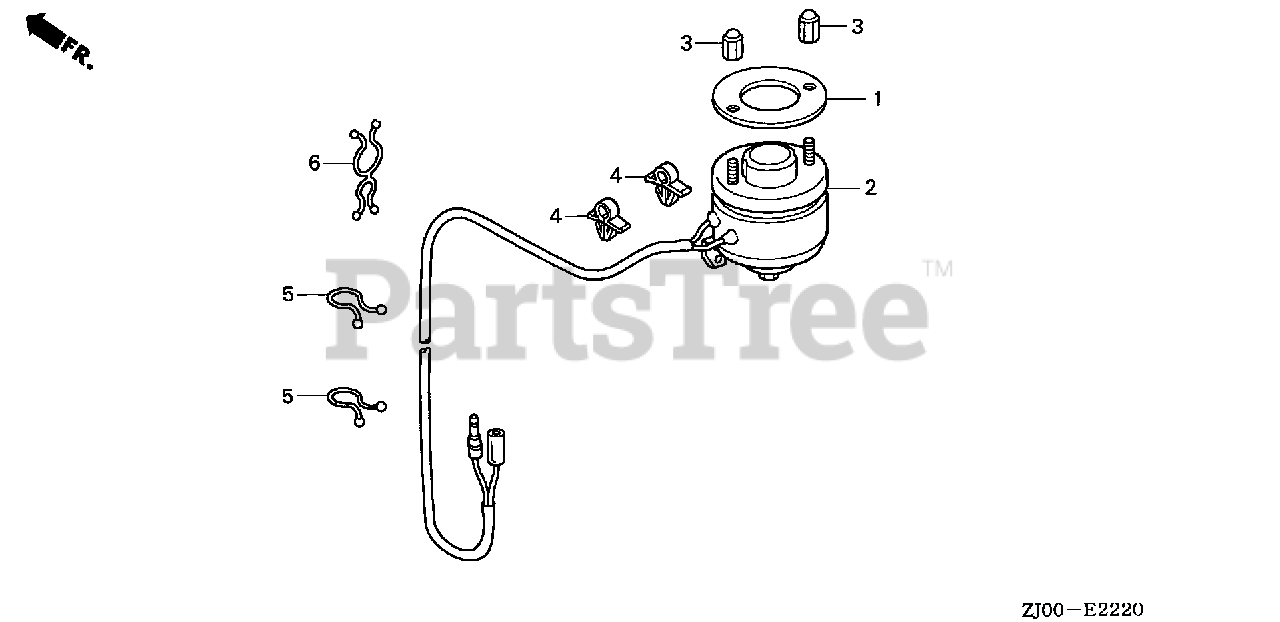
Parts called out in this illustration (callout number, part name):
1	PLATE, SOLENOID
2	SOLENOID ASSY., ROTARY
3	NUT, SPECIAL CAP
4	CLIP, WIRE HARNESS (6MM) (WHITE)
5	PURSE, LOCK (8MM)
6	CLIP, PURSE LOCK
